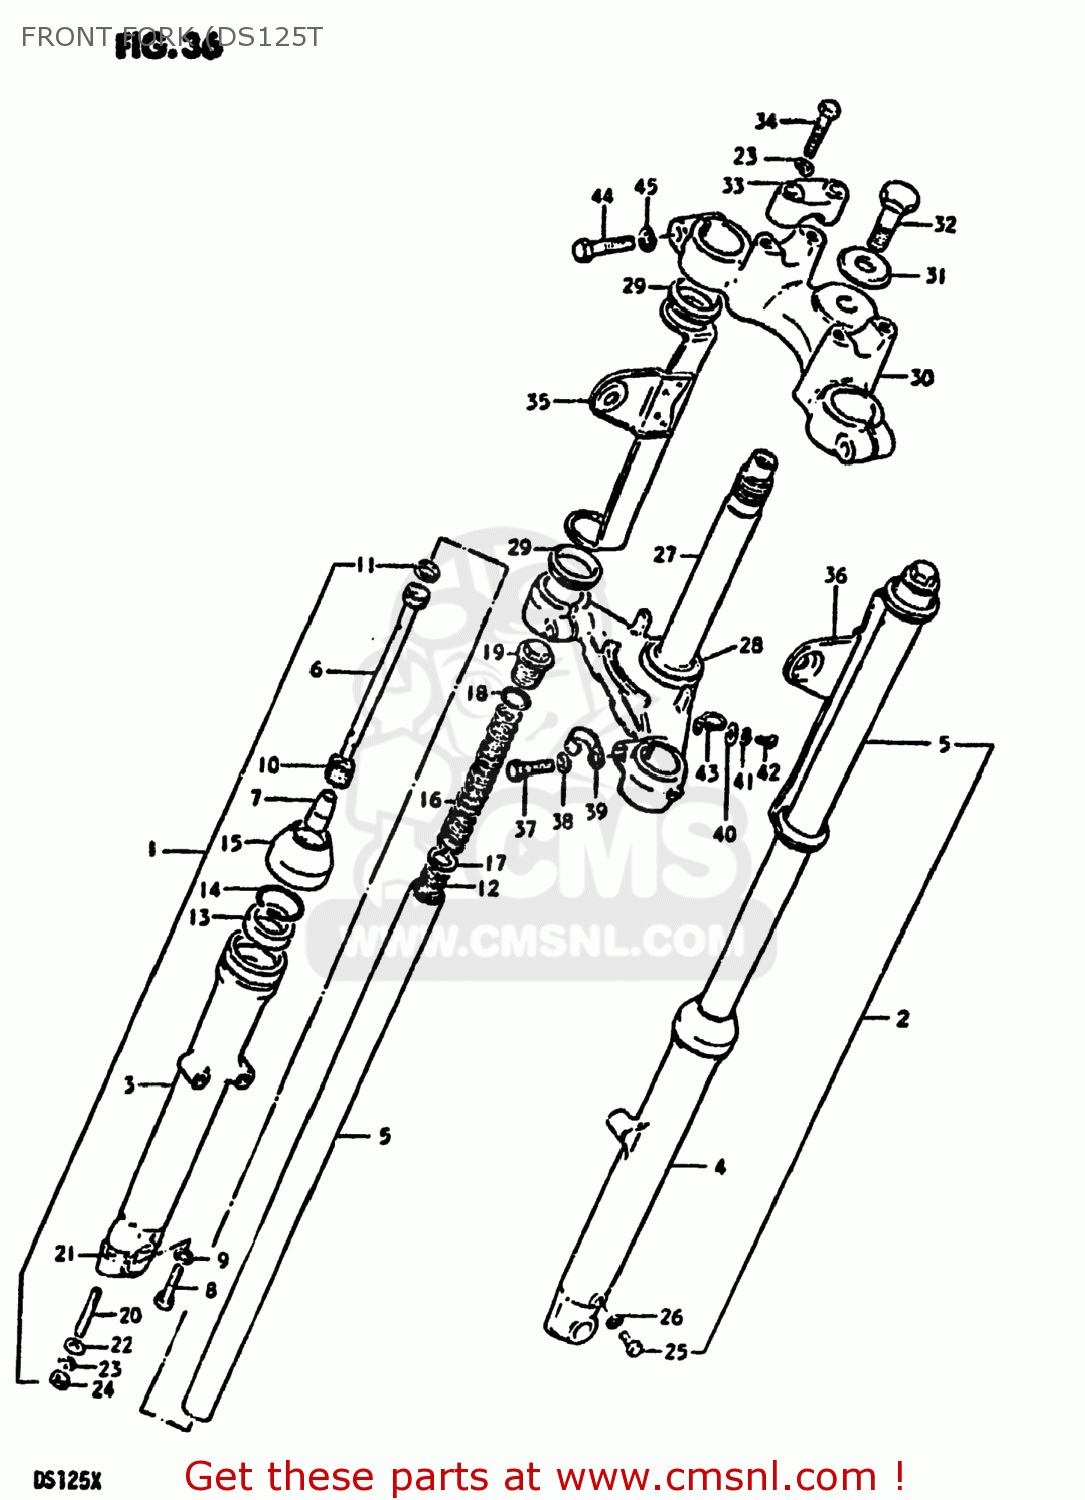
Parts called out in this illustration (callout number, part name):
1	DAMPER ASSEMBLY,RIGHT
2	DAMPER ASSEMBLY,LEFT
3	TUBE,OUTER,R
4	TUBE,OUTER,L
5	TUBE,INNER
6	CYLINDER,FRONT FORK
7	PIECE,OIL LOCK
8	BOLT(8X27)
9	GASKET (NAS)
10	SPRING,FORK REBOUND
11	RING
12	SPRING,FRONT FORK
13	OIL SEAL,FRONT FORK
14	CIRCLIP,FORK OIL SEAL
15	DUST SEAL,FRONT FORK
16	SPRING,FRONT FORK
17	SEAT,SPRING
18	O RING
19	BOLT
20	STUD 8X25
21	HOLDER,AXLE(BLACK)
22	WASHER
23	LOCK WASHER
24	NUT (8MM)
25	BOLT(6X8)
26	GASKET,DRAIN,PLUG (NAS)
27	STEM,STEERING
28	RACE,STEERING OUTER LWR
29	CUSHION
30	HEAD,STEERING STEM(BLACK)
31	WASHER(10.5X30X2.3)
32	BOLT,STEERING STEM HEAD
33	HOLDER,HANDLE UPR
34	BOLT
35	BRACKET,HEADLAMP,RIGHT
36	BRACKET,HEADLAMP,LEFT
37	BOLT
38	WASHER,LOCK 12
39	CLIP
40	WASHER
41	LOCK WASHER
42	SCREW 6X12
43	CLIP
44	BOLT
45	LOCK WASHER
